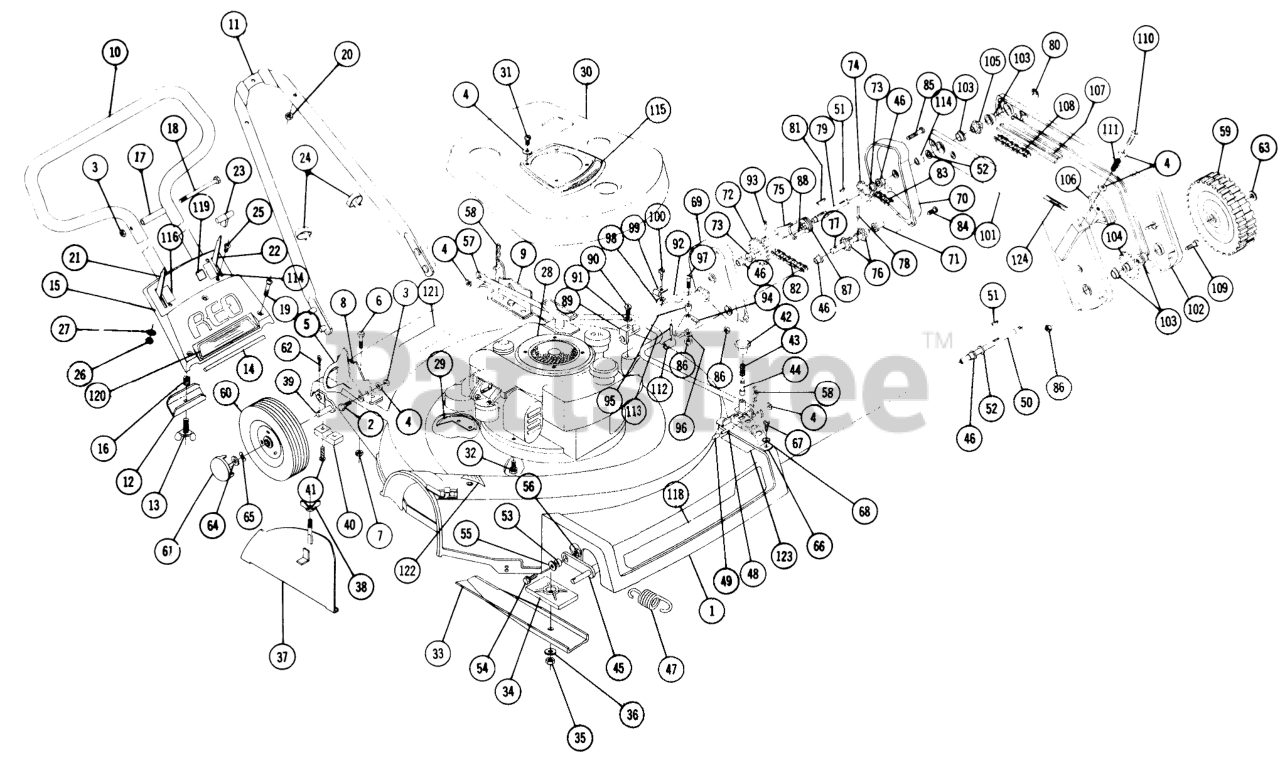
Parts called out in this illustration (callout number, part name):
1	Ass-y Deck
2	Bolt-1/4-20 x 5/8
3	Nut-Nylok
4	Washer
5	Latch-Handle Mounting
6	Bolt 5/16-18 x
7	Nut-Nylok
8	Bracket Handle R.H.
9	Bracket Handle L.H.
10	Handle-Upper
11	Handle-Lower
12	Channel-Clamp
13	Thumb Screw
14	Pin-Handle Pivot
15	Panel-Handle
16	SPRING-COMPRESSION
17	20210 '60&UP 21 SP
18	Bolt Hex 1/4-20 x 4 1/2
19	Screw Oval Head 1/4-20 x 1 1/2
20	Nut Hex 5/4-20 Nylok
21	Ass-y Throttle Control
22	Ass-y. Shift Control
23	Knob
24	Clip-Control
25	Screw #2 Phillips #8-32 x 3/8
26	Nut Hex #8-32
27	Lockwasher
28	Engine
29	Deflector-Muffler
30	Shroud-Engine
31	Screw 1/4-28 x 3/8
32	Screw Hex 5/16-18 x 1
33	Blade
34	Drive Blade
35	Nut Hex 5/8-18 Thin
36	Washer, 5/8
37	Ass-y Leaf Mulcher
38	Nut Wing 1/4-20
39	Ass-y Axle-Rear
40	Cap-Rear Axle Support
41	Screw Hex 1/4-20 x 7/8 Self Tap
42	KNOB
43	Spring
44	PLUNGER
45	Ass-y Height Adjustment Lever
46	BRONZE BUSHING
47	Spring
48	ROLL PIN 1/8 X 1 1/2
49	Cap
50	Axle-Front
51	WOODRUFF KEY
52	Washer-Thrust
53	Spacer
54	Bolt 5/16-18 x 11/4
55	Washer
56	Nut 5/16-18
57	Rod-Wheel Adjustment Link
58	Hairpin
59	Wheel & Tire Assembly
60	Wheel & Tire Assembly
61	Cap-Hub
62	Hairpin
63	Washer
64	Washer
65	Washer
66	Quadrant-Height Adjustor
68	Lockwasher #10 External
69	Case-Transmission R.H.
70	Case-Trans. L.H.
71	BUSHING
72	Sprocket-19 Tooth
73	Bearing
74	Sprocket 12 Tooth
75	Ass-y Yoke & Shaft
76	Sprocket 8 Tooth
77	Shaft
78	Spirol Pin
79	Shaft Output
80	E Ring
81	HI PRO KEY
82	Chain-Roller
83	Chain-Roller
84	Bolt #10-32
85	Bolt #10-32 x 234 Round Head
86	HEX NUT 10-32 E.S.
87	Collar-Shift
88	Spiral Pin
89	Block-Transmission Block
90	Screw Hex 1/4-20 x 1 1/8 Type "F"
91	Lockwasher
92	Bracket Lever-Shift
93	Pin-Groove 7/64 x 1/2
94	Lever-Shift
95	Spacer Pivot
96	Washer-#10 SAE
97	Screw Round Head # 10-32 x 7/8
98	Nut-Tinnerman
99	CLIP-CABLE
100	Screw #10 x 1/2 Type A
101	Housing-Drive R.H.
102	Housing-Drive L.H.
103	BUSHING
104	Ass-y.-Sprocket & Hub
105	Sprocket 8 Tooth
106	Guide-Upper
107	Guide-Lower
108	Chain-Roller
109	Screw-Machine #10-32 x 1 1/4
110	Nut Hex #10-32 Elastic Stop
111	Spring
112	Coupling
113	Roll Pin
114	Spacer
115	Decal
116	Decal-Control Panel
117	Decal-Control Panel
118	MANUAL
119	Decal-Lever Instructions
120	Decal-Regal IV
121	4XC6485 GIS ROTARY
122	Decal-Caution
123	Decal-Height Indicator
124	Decal-Chain Adjustment
